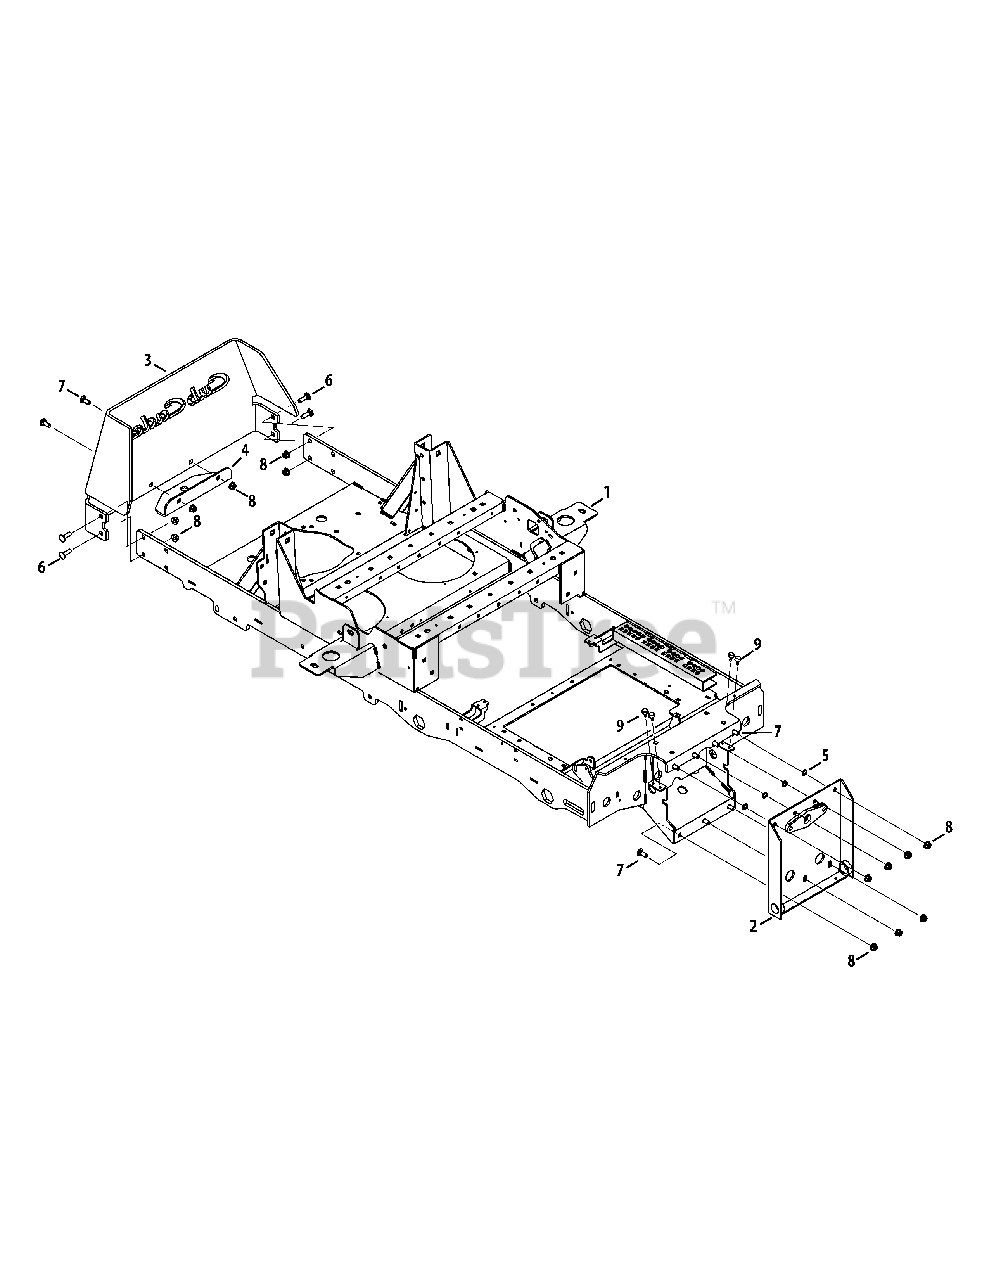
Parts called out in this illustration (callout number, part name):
1	Frame Assembly
2	Front Axle Bracket Assembly
5	Push Nut, 3/8
6	Carriage Bolt, 3/8-16 x 1.25
7	Carriage Bolt, 3/8-16 x 1.00
8	Nylock Nut, 3/8-16
9	Bumper, .62 Dia. x .3
